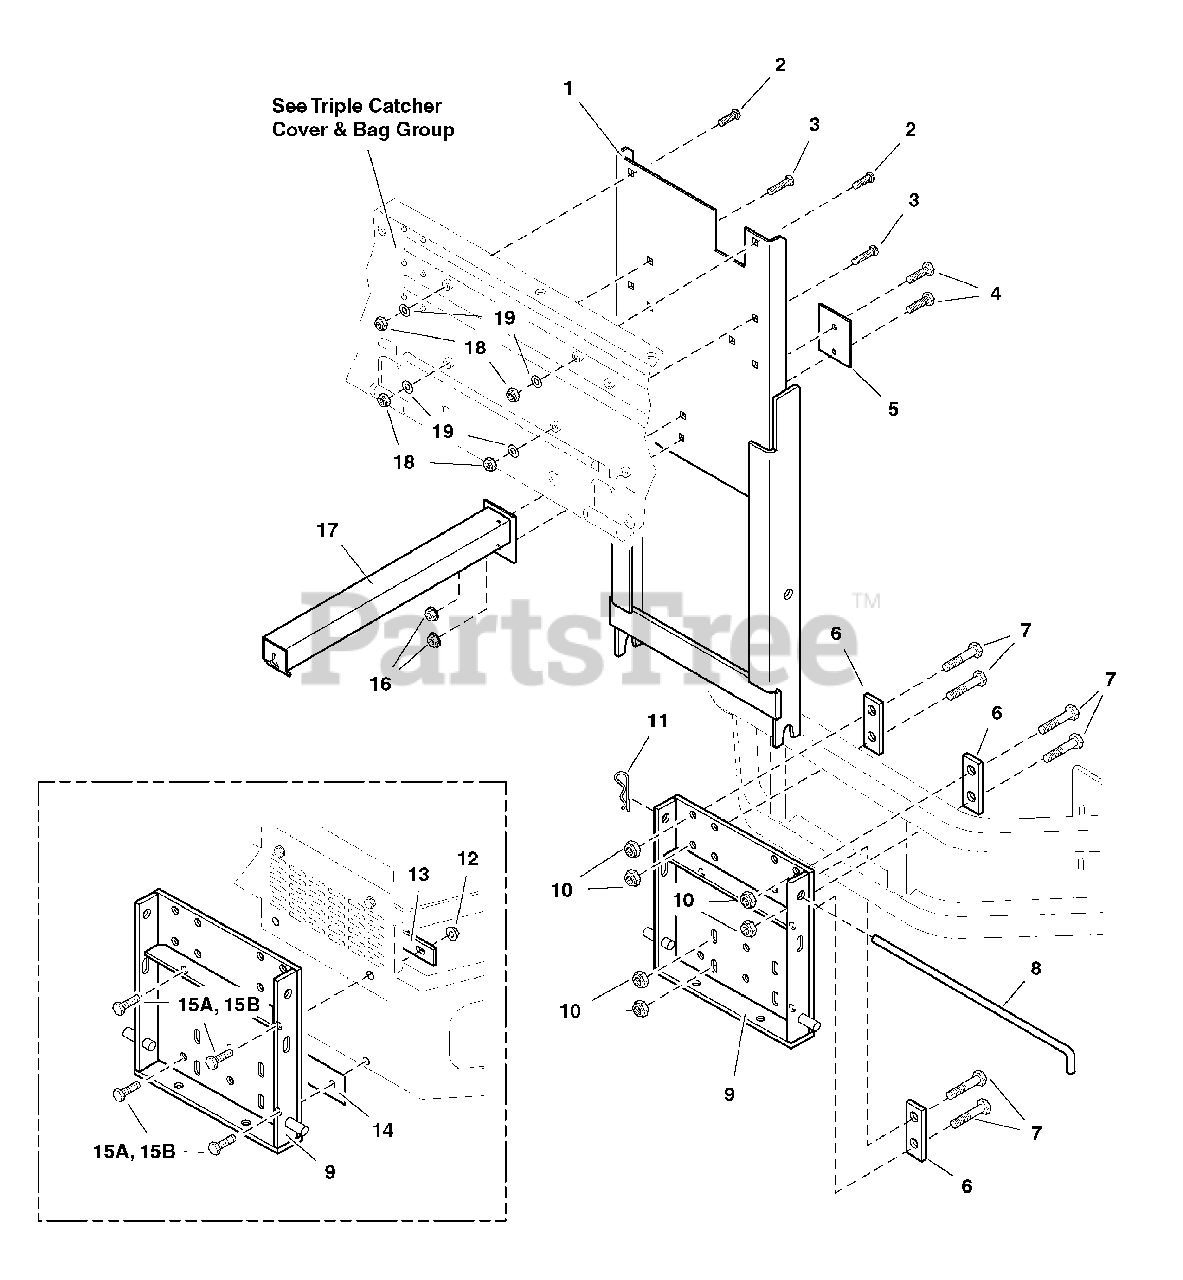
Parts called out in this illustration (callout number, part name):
1	SUPPORT ASSEMBLY
2	CARRIAGE BOLT, 5/16-18 x 3/4
3	CARRIAGE BOLT, 5/16-18 x 1-1/4
4	BOLT, 5/16-18 X 3/4 GD5
5	REINFORCEMENT PLATE
6	BAR CLAMP
7	BOLT, 3/8-16 x 2-1/2
8	HITCH ROD
9	HITCH PLATE
10	NUT, 3/8-16 Hex Nylon Lock
11	HAIR PIN CLIP
12	NUT, 3/8-16 Hex Serrated Flange
13	BUMPER REINFORCEMENT
15A	BOLT, 3/8-16 x 1-1/4
15B	BOLT, 3/8-16 x 2
16	NUT, 5/16-18 Hex Small Serrated Flange
17	COVER LATCH ARM
18	NUT, 5/16-18 Hex Nylon Lock
19	WASHER, 5/16" SAE
